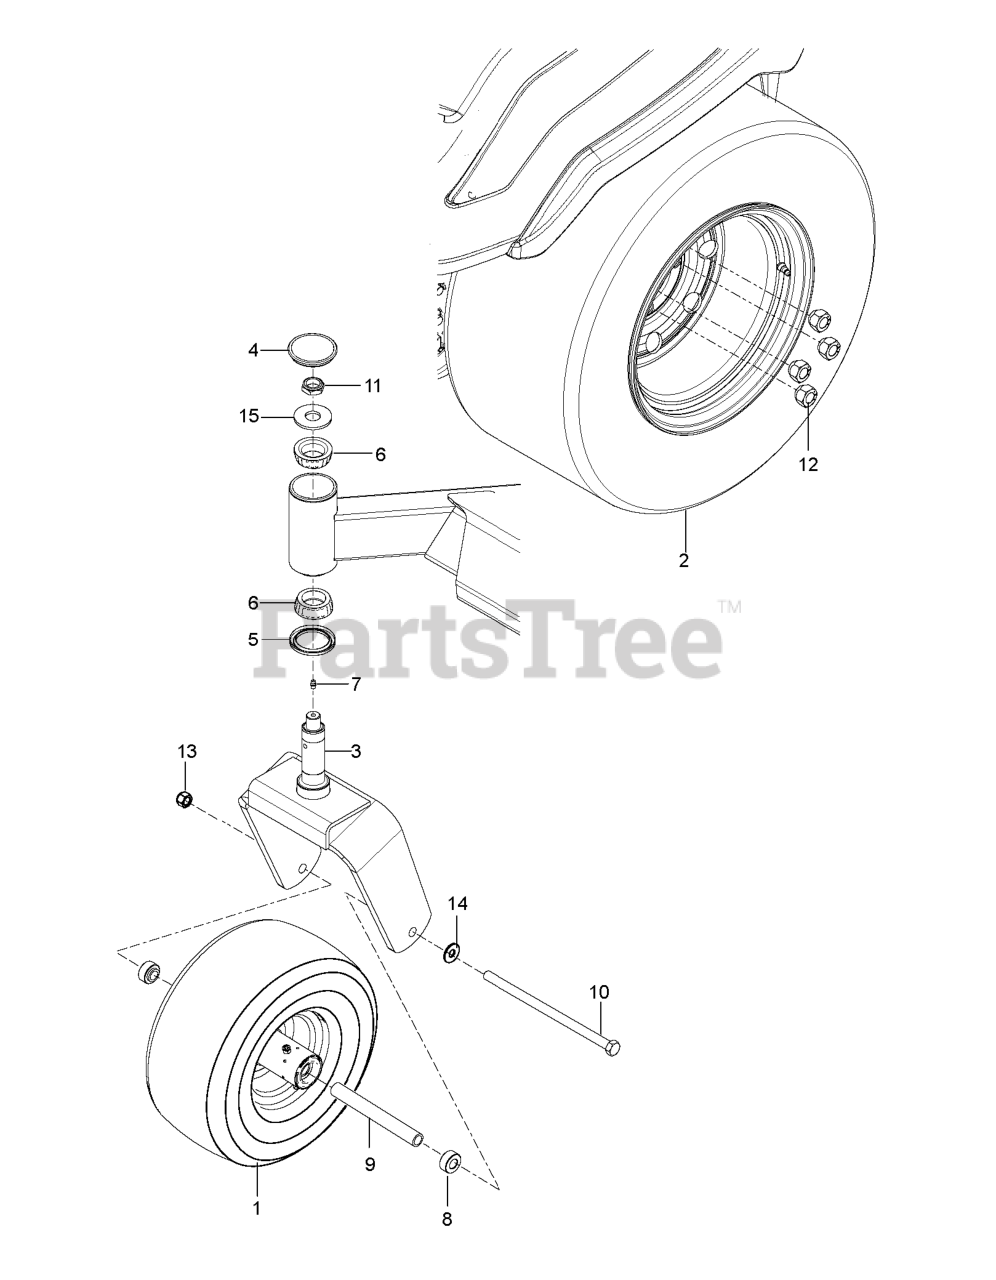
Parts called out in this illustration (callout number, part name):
1	TIRE.13X6.5-6 SILVER X417.SEMI
1	PZ CASTER SERVICE KIT
1	TIRE, 13 X 6.5-6 NO FLAT
2	WHEEL/TIRE.ASM.24X12-12.SILVER
3	FORK.CASTER.ORANGE
5	SEAL, BEARING
6	CONE, LM67048
8	SPACER.AXLE
9	SPACER.HUB
10	HEX SCREW 1/2-13 X 9.5 GR5
11	NUT, 3/4-16 HEX THIN NYLOC ZD
12	NUT.1/2-20.UNF-2B.GR.8.YL
13	NUT, 1/2-13 HEX FLG NYLOC ZD
13	NUT. 1/2-13 HEX CNTRLK GR 5 ZD
14	WASHER 1/2" FLAT
15	WASHER, 3/4 HARDENED
